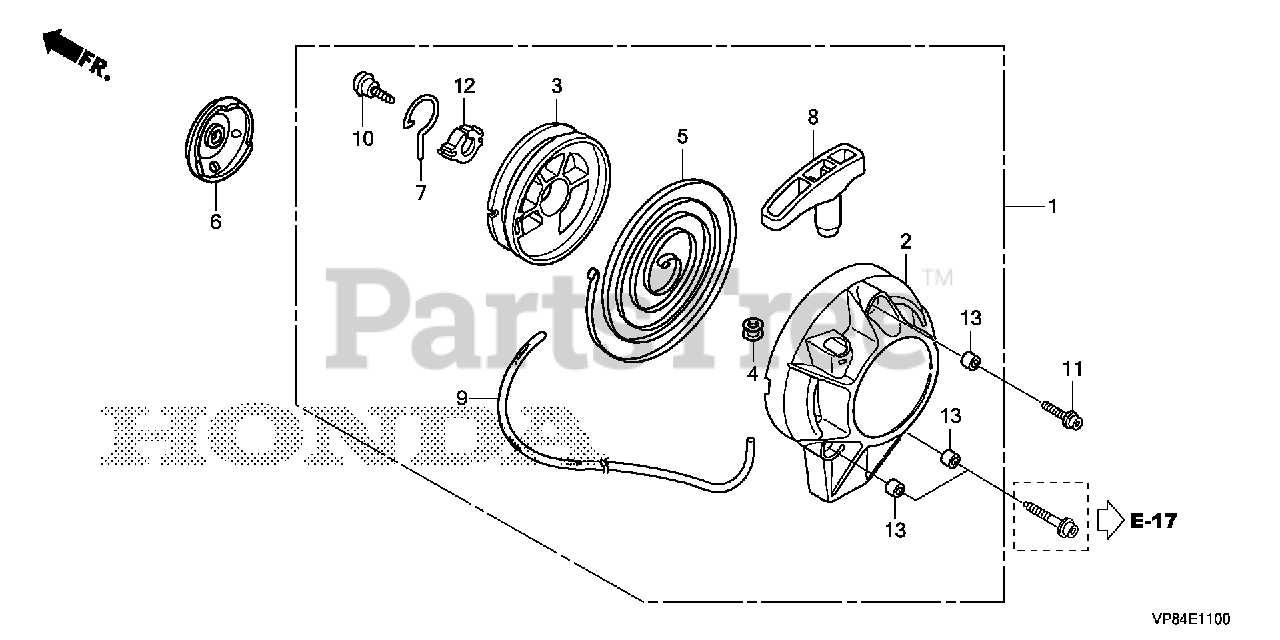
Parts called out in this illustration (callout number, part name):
1	STARTER ASSY., RECOIL (FOR U.S.A.)
1	STARTER ASSY., RECOIL
2	CASE, RECOIL STARTER
3	REEL, RECOIL STARTER
4	GUIDE, ROPE
5	SPRING, RECOIL STARTER
6	PULLEY, RECOIL STARTER
8	KNOB, RECOIL STARTER
9	ROPE, RECOIL STARTER (#3.5X40")
10	SCREW, SETTING
11	BOLT, SOCKET (5X16)
13	COLLAR A, HEAD COVER
